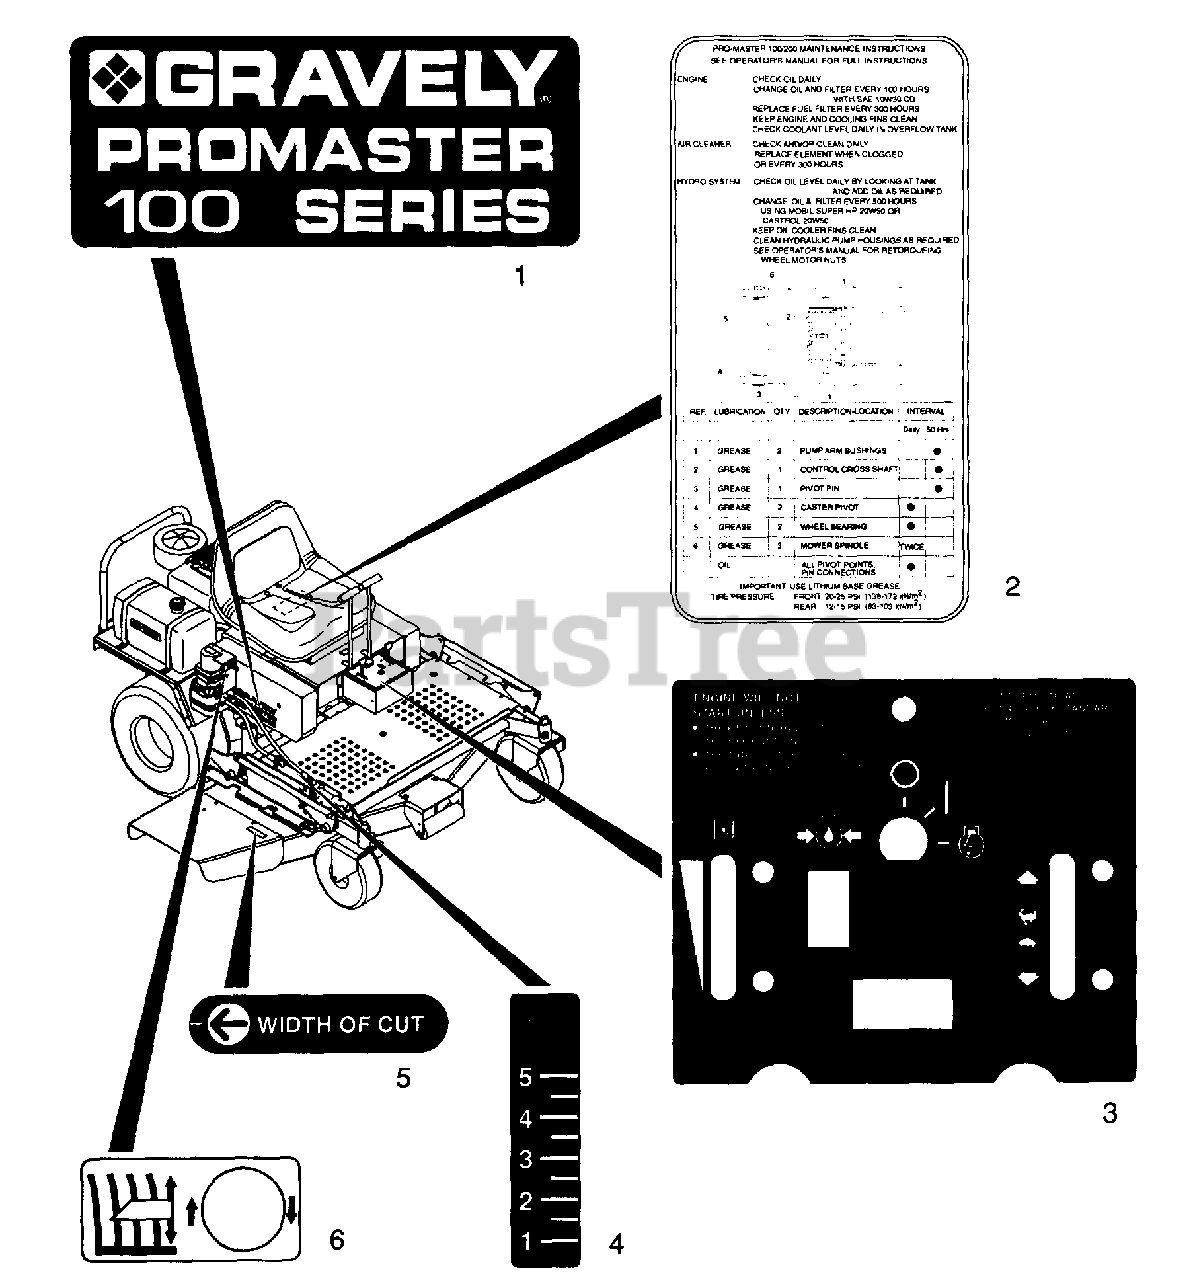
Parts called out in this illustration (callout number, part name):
1	Decal, Promaster 100
2	Decal, PM-100/200 Maintenance
3	Decal, Engine Panel
4	Decal, PM-100/50 Deck Lift (006)
5	Width of Cut Decal
6	Decal, Cutting Height Adjustment (006)
